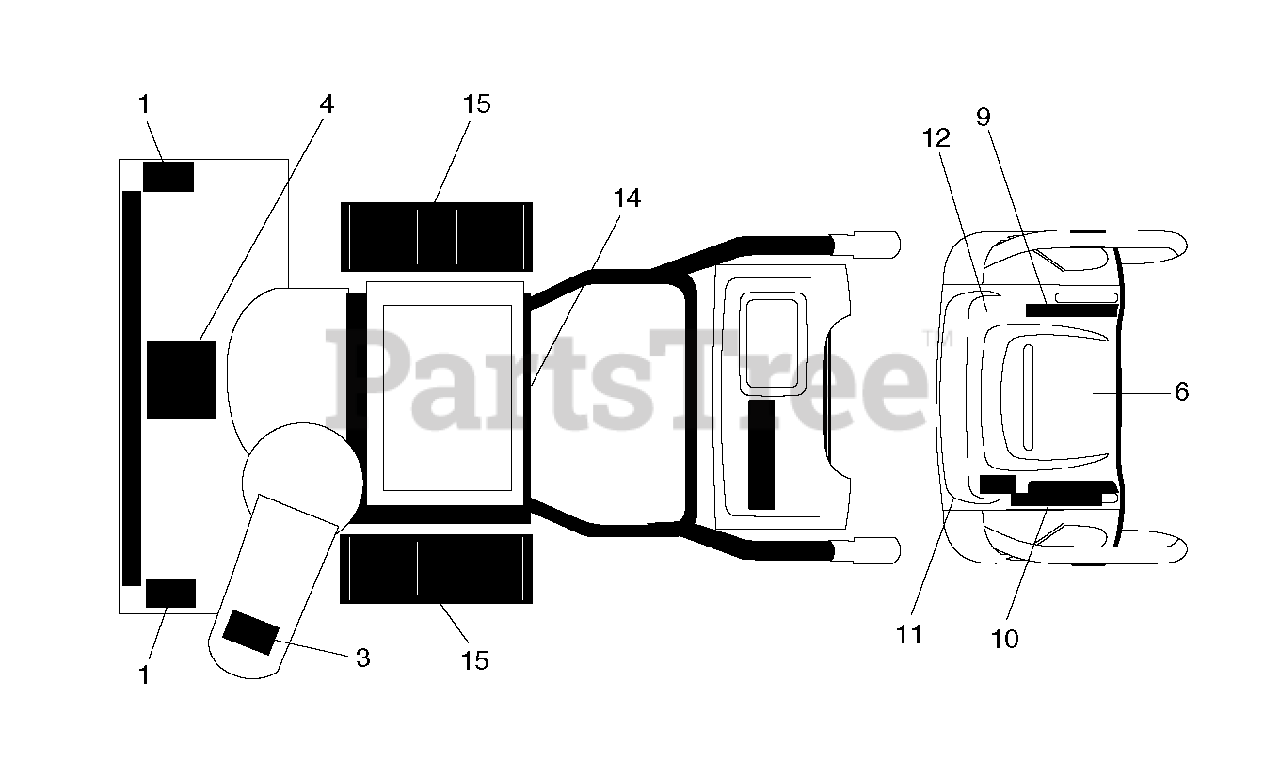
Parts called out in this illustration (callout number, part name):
1	DECAL.AUGER.SAFETY.
3	DECAL.CHUTE.SAFETY.
4	DECAL.AUGER."
9	DECAL.CONS.RT.SPD/LEV/PWRST.
10	DECAL,LHTRIGGER
11	DECAL,HEIGHTADJUST
12	DECAL.CONSOLE.HAND.WARMER
14	DECAL.FENDER
15	DECAL.BELT.GUARD.
